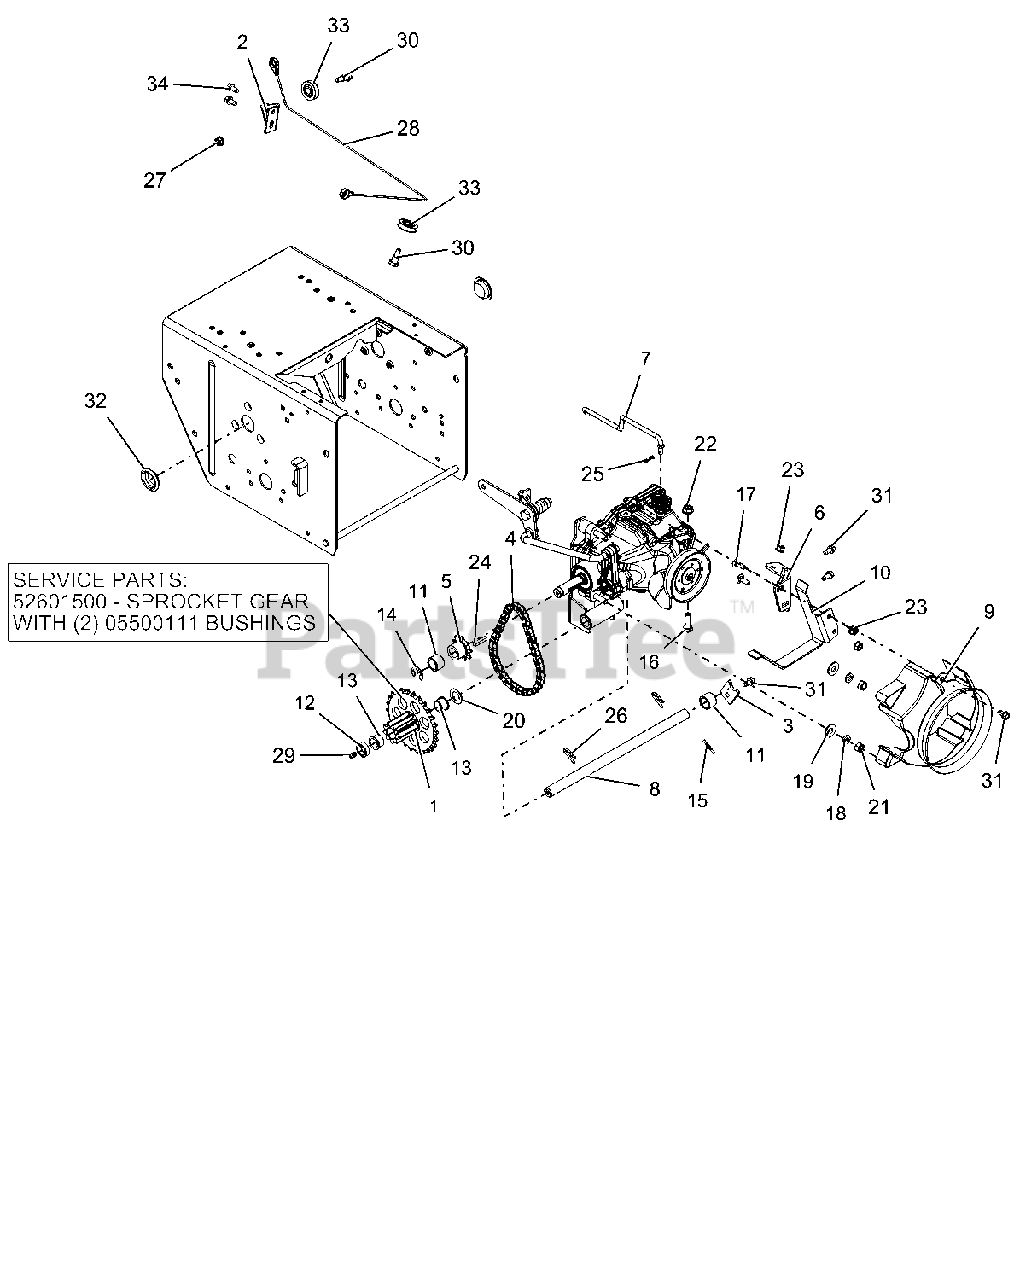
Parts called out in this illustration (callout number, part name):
1	BSHG-FLG .625X.750X.500X.875
1	PINION & SPROCKET
1	PINION & SPROCKET W/BUSHINGS
2	BRACKET, CABLE PULLEY
3	TAB, ANTI ROTATION
4	CHAIN - #41, 32 PITCHES
5	SPROCKET, PINION 9T W/KEY
6	BRACKET, CLUTCH CABLE
7	ROD, HYDRO BYPASS
8	SHAFT, PINION - HARDENED
9	SHROUD, HYDROGEAR RT-310
10	FINGER, BELT - FLAT
11	SPACER, .635X.880X.611
12	BSHG-SLV, .635X.880X.305
13	BSHG-FLG .625X.750X.500X.875
14	RG-RTNG-EXT .625X.042
15	PIN-GRV .125X1.00 TP E ALLOY
16	BLT-HEX .31-18X1.00 GR5 YWZC
17	BLT-RDHDSQNK .25-20X.75 G5YZ
18	WSHR-LK .312X.097 HVY YWZC
19	WSHR-FL-STL.38X.875X.083 YWZC
20	WSHR-FL-STL .630X1.005X.062 YZ
21	NUT-HEX .31-18 YWZC
22	NUT-LK-TOP-FLG .31-18 YWZC
23	NUT-LK-TOP-FLG .25-20 YWZC
24	KEY-SQ .188X1.0X.188 SAE 8630
25	PIN-HAIR INT .06X.18X.77
26	PIN, SPRING CLIP
27	NUT-LK-TOP-FLG .25-20 YWZC
28	CABLE, TRACTION, HYDRO PRO
29	ZERK,FITTING .25X.125 DRIVE IN
30	BOLT, SHLDR-.375X.375X.25-20
31	SCR-TAP .25-20X.50 HWH TR YWZ
32	PLUG, HOLE - 1.125"
33	PULLEY, CABLE
34	SCR-TAP .25-20X.50 HWH TR YWZ
